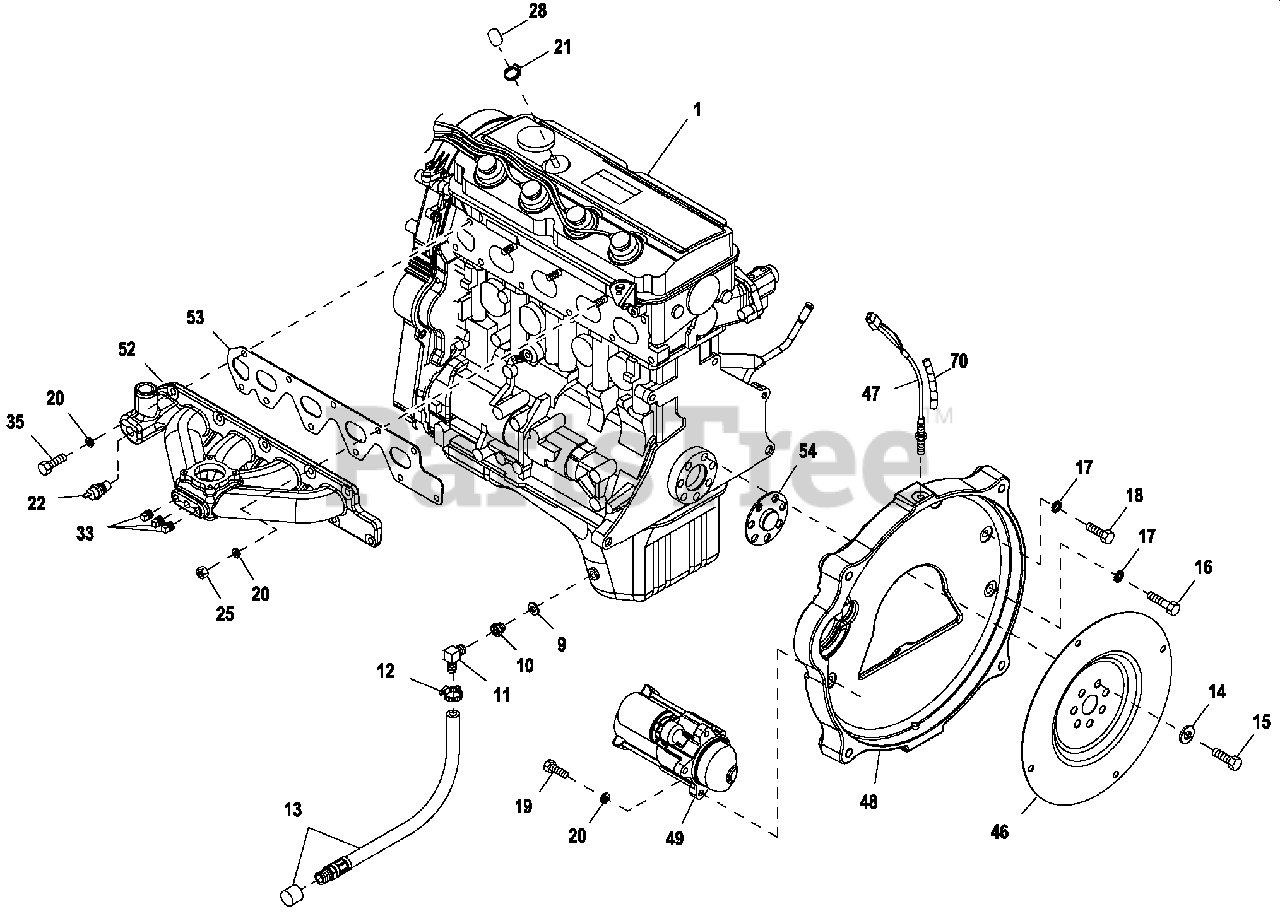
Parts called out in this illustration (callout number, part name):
1	ENGINE 2.4L G2 CERTIFIED
2	WASHER LOCK M10
3	SCREW HHC M8-1.25 X 35 G8.8
4	SCREW SHC M14-1.5 X 35 G10.9
5	ALTERNATOR DC W/O U T P ULLEY
6	U PR BRKT HEAT SHIELD 2.4L 36KW
7	ADAPTOR 1/8NPTF TO 1/8BSPT
8	SWITCH OIL PRESSU RE 10 PSI 2 POL (R-PANEL)
20	WASHER LOCK M8-5/16
23	WASHER FLAT 5/16-M8 ZINC
24	ASSEMBLY DIPSTICK G2.4L
26	WASHER FLAT 3/8-M10 ZINC
27	ASSY DIPSTICK TU BE 2.4 G2
29	SCREW SHC M8-1.25 X 25 G12.9
30	TEE STREET 1/8NPT BRASS W/VS
31	TU BE TU RBO OIL RETURN G2 36KW
32	SCREW HHTT M6-1.0 X 12 ZINC
34	SCREW HHC M10-1.5 X 120 C8.8
35	SCREW HHC M8-1.25 X 25 G10.9
36	FILTER 1.5L/2.4L G2 OIL
37	COIL-2.4L G2 IGNITION
38	N U T HEX M10-1.25 G8 YEL CHR
39	HEAT SHEILD INNER 2.4L G2 36K
40	RIVET POP .125 X 0.337 STEEL
41	O-RING SIZE 9.0MM X 2.0MM NITR
42	SCREW HHC M10-1.25 X 20 C8.8
43	SCREW HHM #10-32 X 1-1/4
45	MANF-EXH (MACH. CASTING)
47	ASSY MAGPICK U P(3/8-24 MALE)
50	CAM SENSOR PIN ASSY
51	COVER CAM GEAR G2 REWORKED
56	SCREW HHC M8-1.25 X 16 C8.8
57	BRACKET ASM-2.4L COIL G2
58	WASHER LOCK #10
59	ADAPTER 2.4L CRANKSHAFT MACH
60	BELT SERPENTINE 37.0" (1800 RPM)
61	P U LLEY DC ALTERNATOR (1800 RPM)
62	WASHER FLAT #10 ZINC
63	COND UIT THERMAL FLEX 13MM ID
64	PLATE "HOT"
65	SCREW HHC M8-1.25 X 70 G8.8
66	SHIELD-MANIFOLD 2.4L G2 36KW
67	DECAL SORE EPA CERTIFICATION
69	TIE WRAP U L 7.4"X .19" BLK
70	CONDUIT FLEX .25"ID
71	SPARK PL U G WIRE SET 2.4L G2 IG
72	HEAT SHIELD OU TER 2.4L G2 36K
73	SCREW HHC M8-1.25 X 65 C8.8
74	BRKT-EXH MANF 2.4L 36KW
75	LWR BRKT ASM HT SHIELD G2 36KW
76	PLUG SPARK
77	NUT HEX M10-1.5 G8 YEL CHR
78	SPACER DC ALTERNATOR PULLEY
